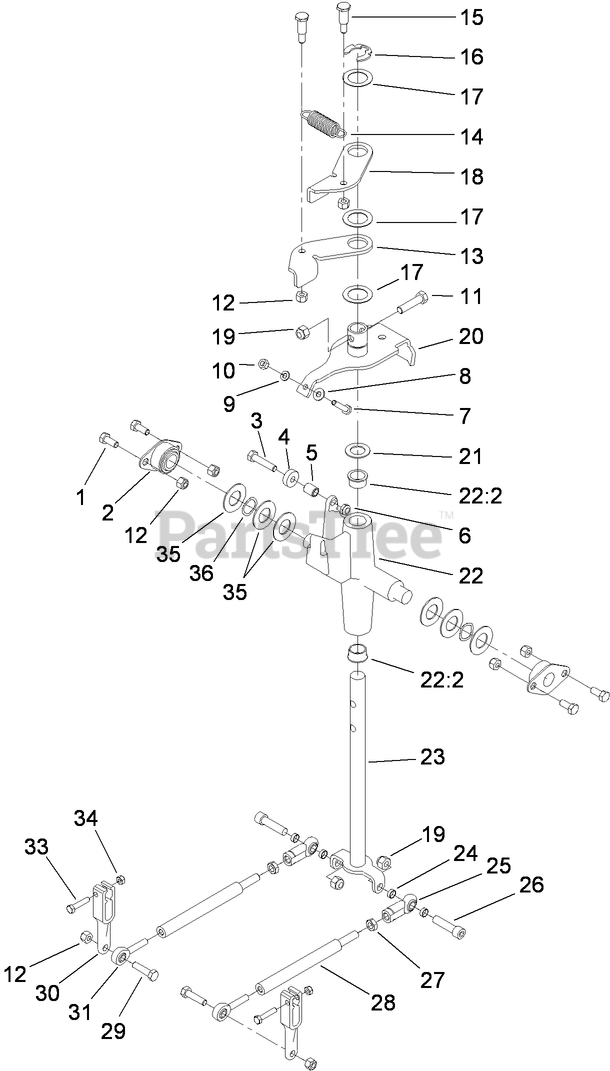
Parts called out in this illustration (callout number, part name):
1	SCREW-HH
2	BUSHING
3	SCREW-HH
4	BEARING-BALL
5	SPACER-LEVER, CONTROL
6	NUT-LOCK, NI
7	SCREW-HH
8	WASHER-FLAT
9	WASHER-LOCK
10	NUT-HEX
11	SCREW-HH
12	NUT-LOCK, NI
13	LEVER-RETURN, RH
14	SPRING-EXTENSION
15	SCREW-SHOULDER
16	RING-RETAINING
17	WASHER-PLAIN
18	LEVER-RETURN, LH
19	NUT-LOCK, NI
20	LEVER-PIVOT
21	WASHER-THRUST
22	CONTROL SUPPORT ASM
22:2	BEARING-FLANGE
23	ROD-DRIVE
24	SPACER
25	JOINT-BALL END, LH
26	SCREW-HSH
27	NUT-HEX JAM, LH
28	ROD-LINKAGE
29	SCREW-HH
30	ARM-CONTROL, PUMP
31	BEARING-ROD END, RH
33	SCREW-HH
34	NUT-LOCK
35	WASHER-FLAT
36	WASHER-SPRING, WAVE
